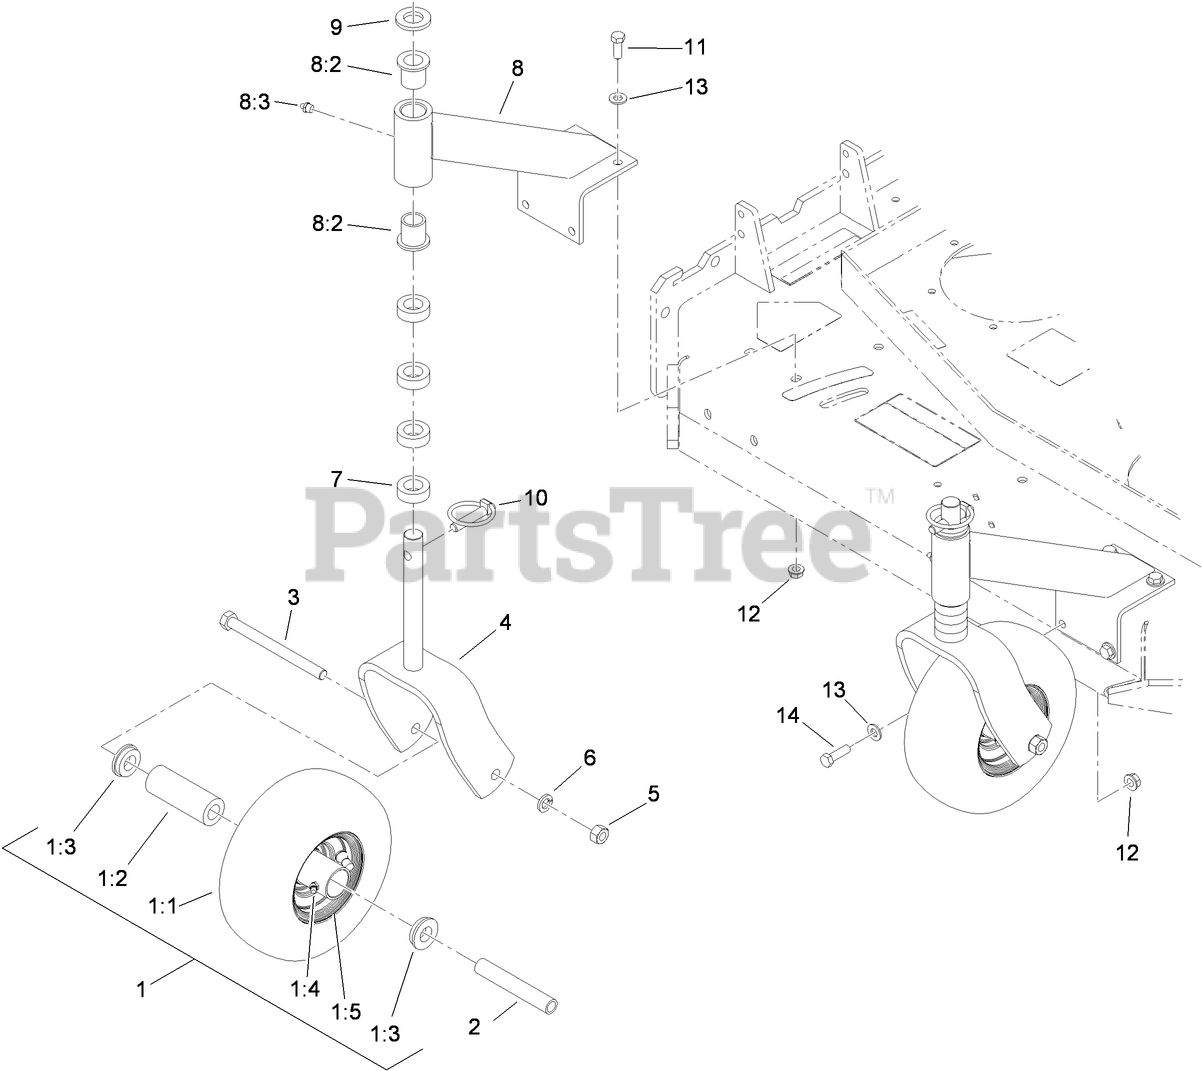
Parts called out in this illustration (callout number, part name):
1	WHEEL AND TIRE ASM
1:1	TIRE
1:2	BEARING
1:3	BUSHING
1:4	FITTING-GREASE
1:5	WHEEL
2	SPACER
3	SCREW-HH
4	FORK
5	NUT-HH
6	WASHER-LOCK
7	SPACER-CASTER
8	SUPPORT ASM
8:2	BEARING-FLANGED
8:3	FITTING-GREASE
9	WASHER-FLAT
11	SCREW-HH
12	NUT-HF, NI
13	WASHER-FLAT
14	SCREW-HH
